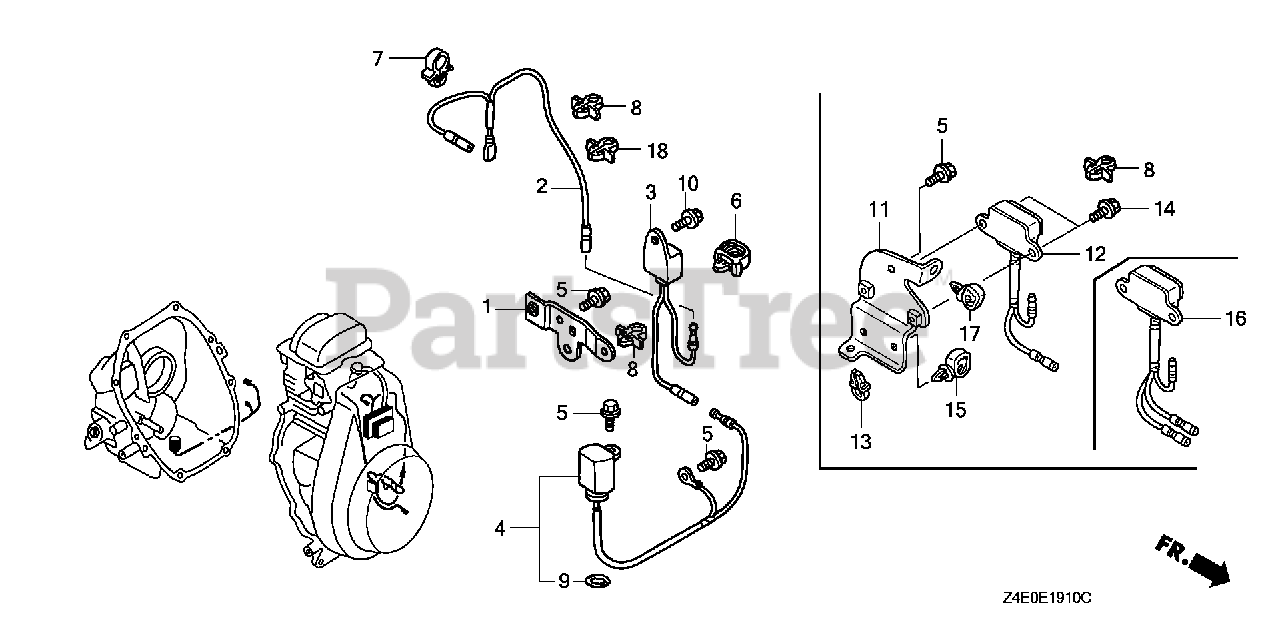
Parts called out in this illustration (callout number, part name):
1	BRACKET, OIL ALERT UNIT
2	WIRE, STOP SWITCH
3	ALERT UNIT, OIL
4	SWITCH ASSY., OIL LEVEL
5	BOLT, FLANGE (6X14)
6	CLIP, WIRE HARNESS (10MM)
7	CLIP B, CABLE
8	CLIP, CABLE (A)
9	O-RING (11.8X2.4)
10	BOLT, FLANGE (6X8)
